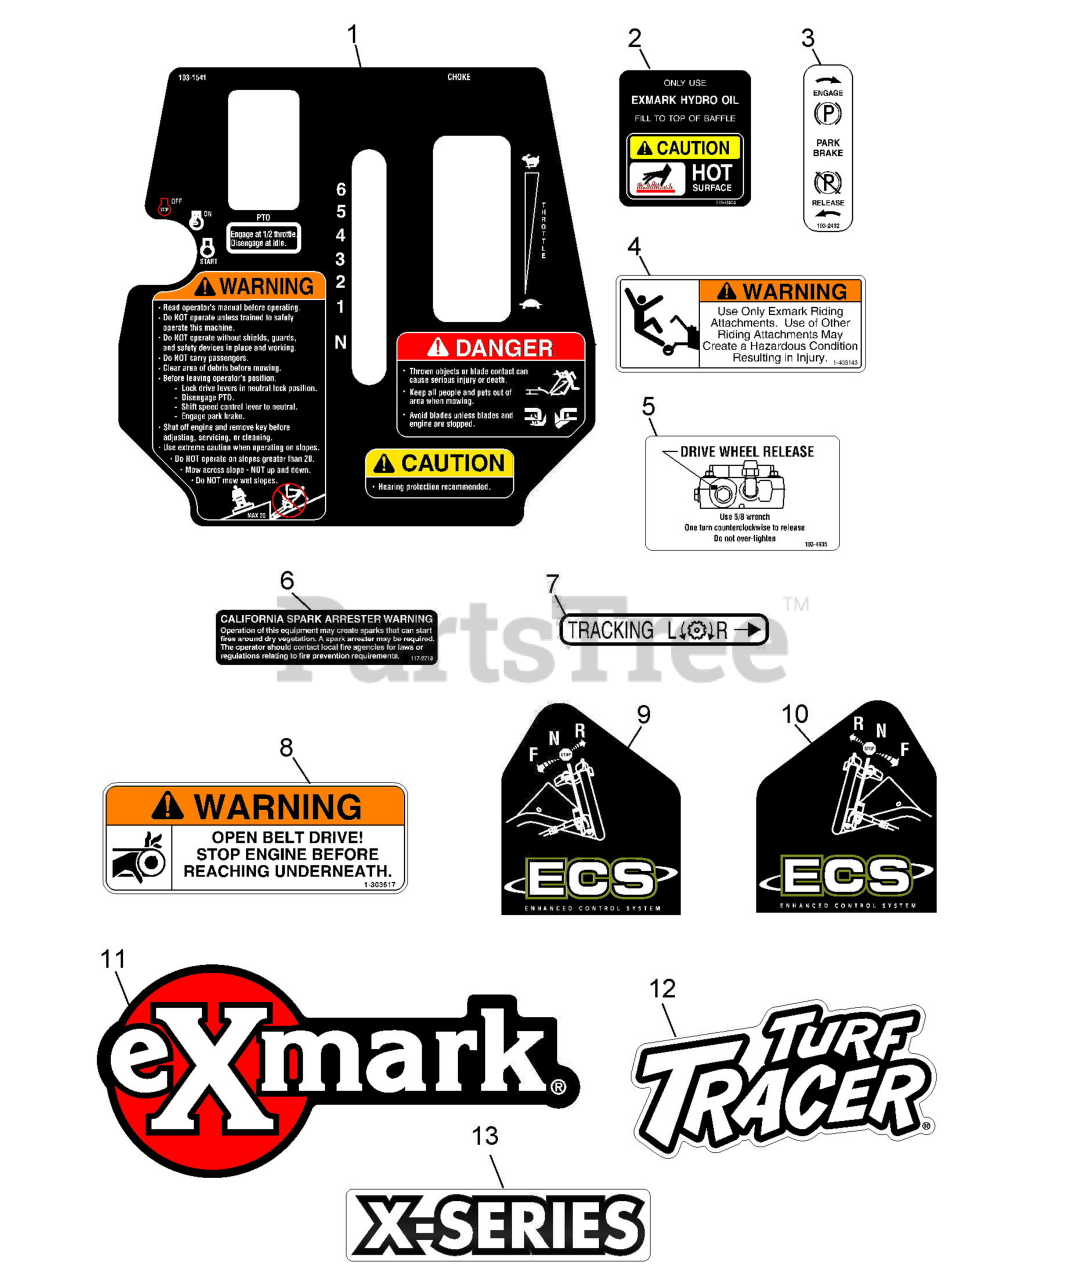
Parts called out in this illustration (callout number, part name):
1	DECAL,TTH ECS CONSOLE
2	DECAL-HYDRAULIC TANK
3	DECAL,SULKY WARNING
4	DECAL,PARKING BRAKE
5	DECAL,DRIVE RELEASE
6	DECAL-ARRESTER, SPARK
7	DECAL,TRACKING ADJUST
8	DECAL,BELT DRIVE
9	DECAL,LH ECS INSTRUCTION
10	DECAL,RH ECS INSTRUCTION
11	DECAL,EXMARK LOGO
12	DECAL,TTH MODEL
13	DECAL-X-SERIES
